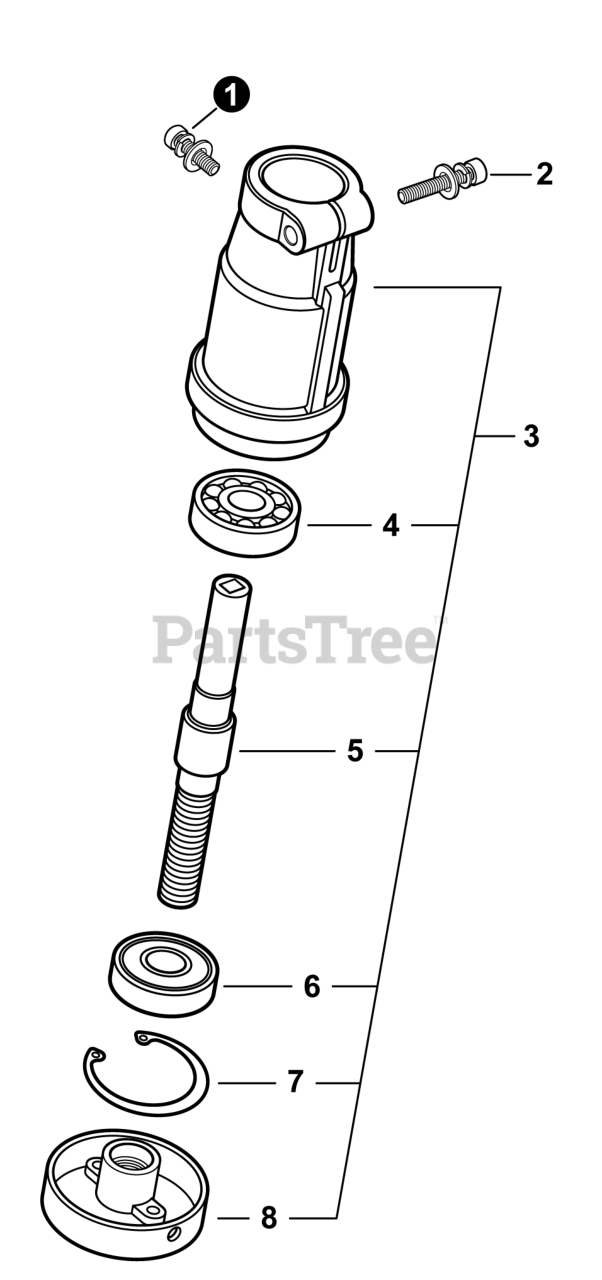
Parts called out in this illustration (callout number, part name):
1	BOLT, TORX 4x8
2	BOLT, TORX 5x25
3	GEAR CASE ASSY
4	BEARING, BALL 6200
5	SHAFT, GEAR
6	BEARING, BALL 6200
7	E-RING 30
8	PLATE, ADAPTOR - UPPER
